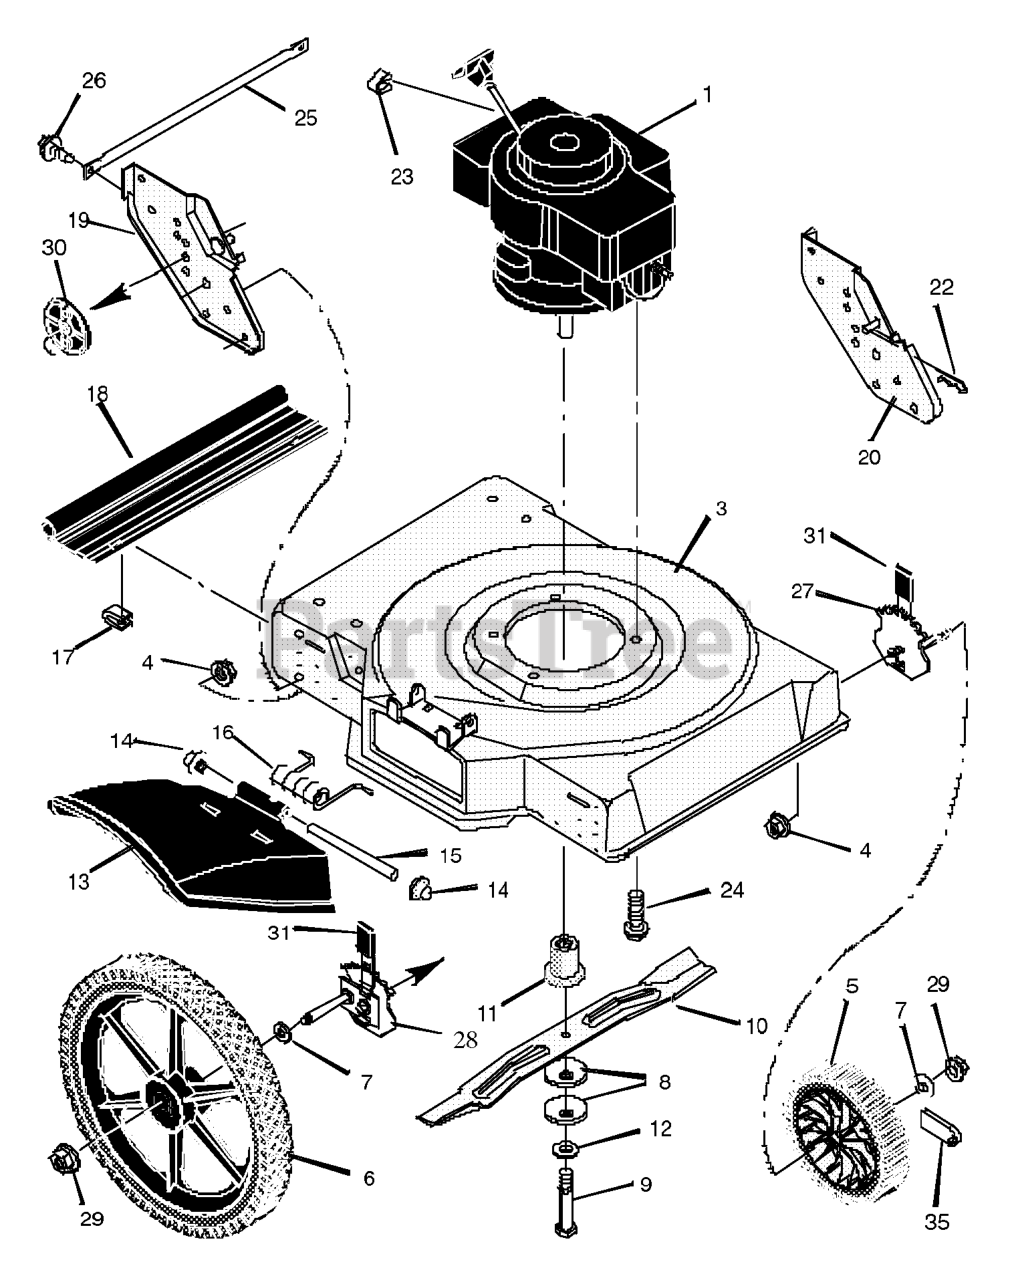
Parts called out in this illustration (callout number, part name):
1	Engine *
3	Housing
4	Nut, Hex
5	Wheel and Tire, Front *
6	Wheel and Tire, Rear *
8	Washer, Blade
9	Bolt, Hex
11	Blade Adapter
13	Deflector, Chute
14	Push On Cap
15	Pin, Pivot
17	Retainer
18	Deflector, Rear
19	Bracket, Right Wheel
20	Bracket, Left Wheel
22	Pin, Hair
23	Stop, Rope
24	Bolt, Engine
27	Height Adjuster, Front
28	Height Adjuster, Rear
29	Locknut
35	Hub Cap
